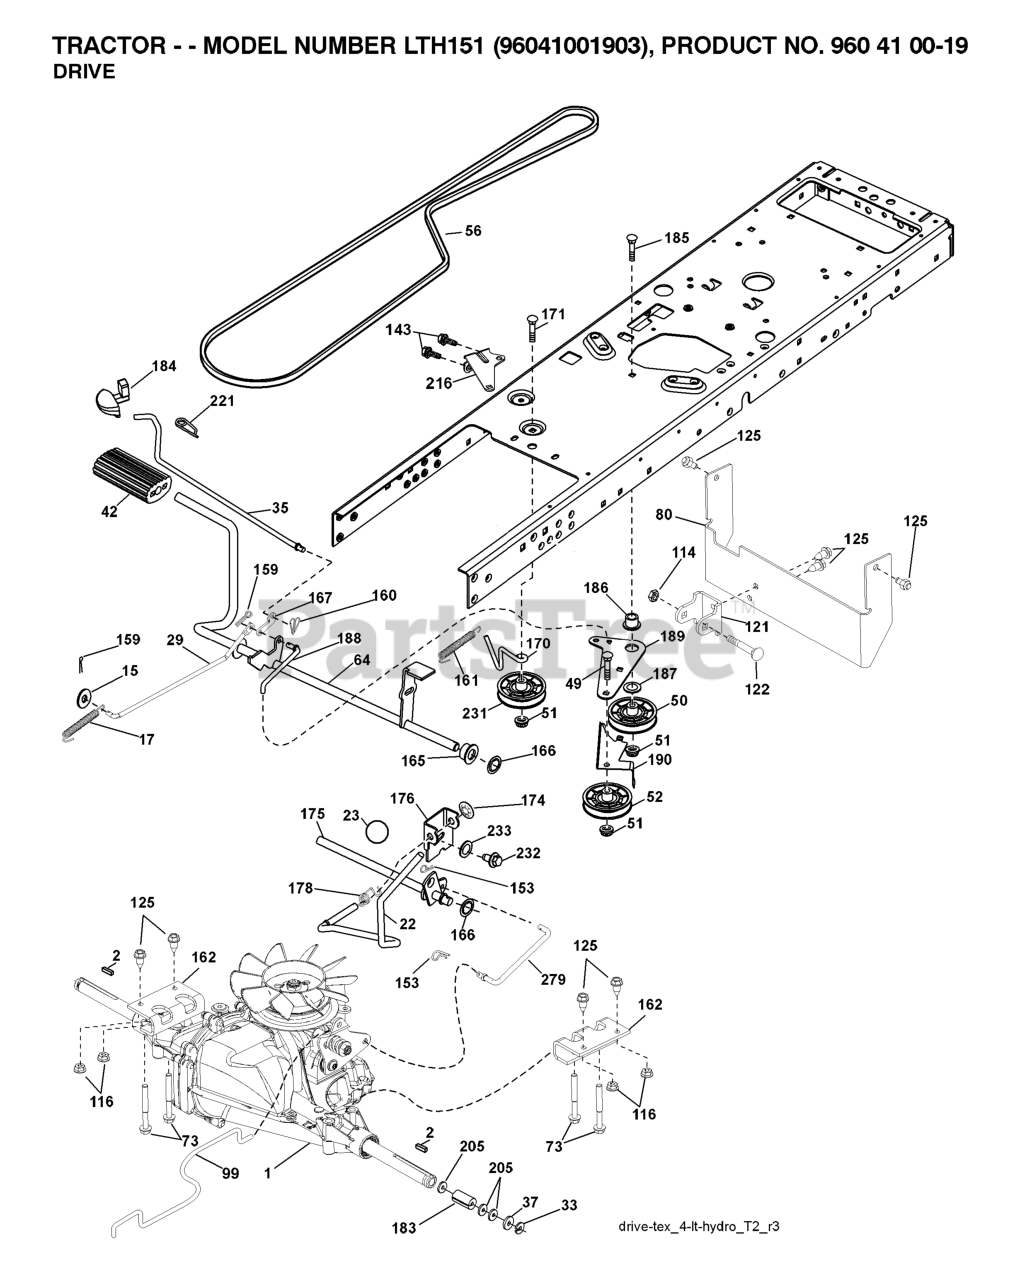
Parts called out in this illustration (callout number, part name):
2	SQUARE KEY
15	WASHER
17	SPRING.BRAKE.HG3000/3500
22	ROD.SHIFT.FENDER.TLT.2006
23	KNOB.DUCKHEAD.1/2
29	ROD.BRAKE.T2.TEX
35	ROD.CNTRL.PARK.PREDATOR.LT.TEX
42	PEDAL COVER T
50	IDLER.FLAT.910.OFFSET
51	NUT LOCK FLG 3/8-16 UNC
52	IDLER.V-GROOVE.910.OFFSET
64	SHAFT.ASM.PEDAL.BRAKE.
73	BOLT HEX 5/16-18 GR 5
80	RP.STRAP.TORQUE.FS.T2
99	ROD.ASM.BYPASS.SPRING.T2.FS
114	NUT.71038.31-18.HEX.NYLOCK
116	NUT LOCK HEX FLANGE 5/16-18
121	BRACKET STRAP TORQUE
122	BOLT.5/16-18X2.5
125	SCREW
143	Screw 5/16-18 x 1/2 Hex, Self Tapping 5/16-18 x 1/2
153	RETAINER M
159	COTTER PIN
160	RETAINER CLIP
161	SPRING, RETURN LT
162	ADAPTER.TRANSAXLE.T2.TLT.DRWBR
165	BUSHING.SHAFT.BRAKE.HAND
166	NUT.PUSH.625.2006
167	LATCH.BRAKE.SPRING
170	KEEPER.CENTER SPAN.1.688
174	NUT.PUSH.500.2006
175	SHAFT.ASM.SHFT.T2.TLT
176	ARM.CLEVIS.ROD.SHIFT
178	SPRING.SHIFT.GT2006
183	SPACER, AXLE PVST
184	HANDLE PARKING BRAKE
186	SPACER.RETAINER
187	WASHER 12/32X2X10GA
188	RP.LINK.CLUTCH.GROUND.DRIVE
189	BELLCRANK.GROUND.DRIVE.TEX.
190	KEEPER.BELLCRANK.DRIVE
216	BRACKET.PULLEY.IDLER.W/TEX
221	RETAINER.SPRING.CLIP.H
231	IDLER.V-GROOVE.1.688.OFFSET
232	BOLT FIN HEX 7/16-14 X 1
233	WASHER SERRATED
279	LINK SHIFT
